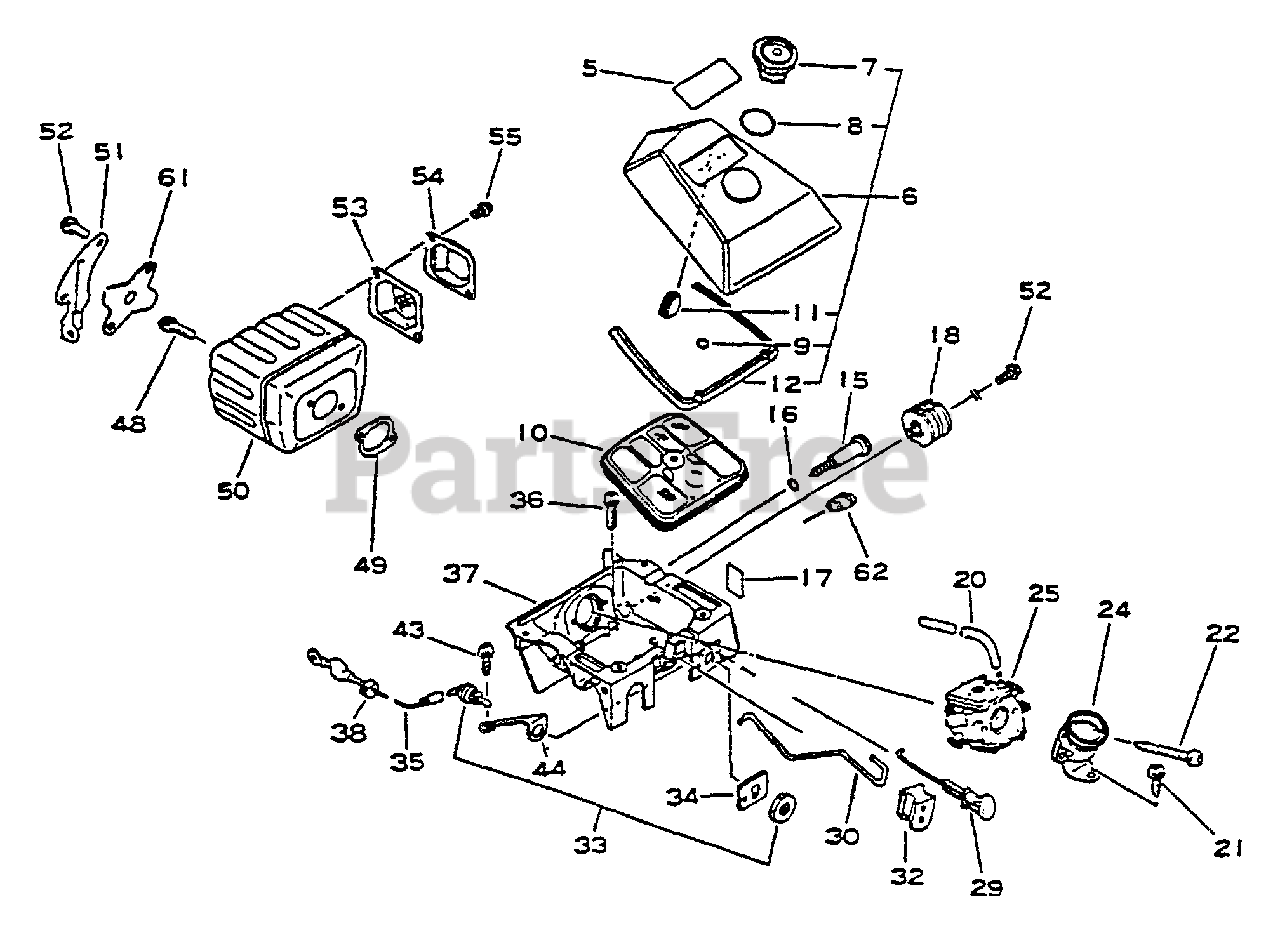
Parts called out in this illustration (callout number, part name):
5	LABEL
6	AIR FILTER COVER ASSY
7	THUMBSCREW
8	O-RING - 22
9	O-RING - 11
10	FILTER, AIR
12	SEAL
15	SCREW, IDLE ADJUST
16	O-RING - 7
17	LABEL - IDLE
18	CUSHION
20	FUEL PIPE KIT
21	SCREW - 5X14
22	SCREW - 5X55
23	PLATE, PREVENT
24	ADAPTOR, INTAKE
25	CARBURETOR HDA-53
29	ROD, CHOKE
30	ROD, THROTTLE
32	GUIDE, THROTTLE ROD
33	IGNITION SWITCH ASSY
34	LABEL - STOP
35	LEAD - GROUND
36	SCREW - 5X20
37	CASE, CARBURETOR
43	SCREW - 4X10
44	TERMINAL - GROUND
48	SCREW - 5X20
49	GASKET, EXHAUST
50	MUFFLER
51	BRACKET, MUFFLER
52	SCREW - 5X14
53	SCREEN, SPARK ARRESTOR
54	GUIDE, EXHAUST
55	SCREW - 4X10
61	COVER, MUFFLER
